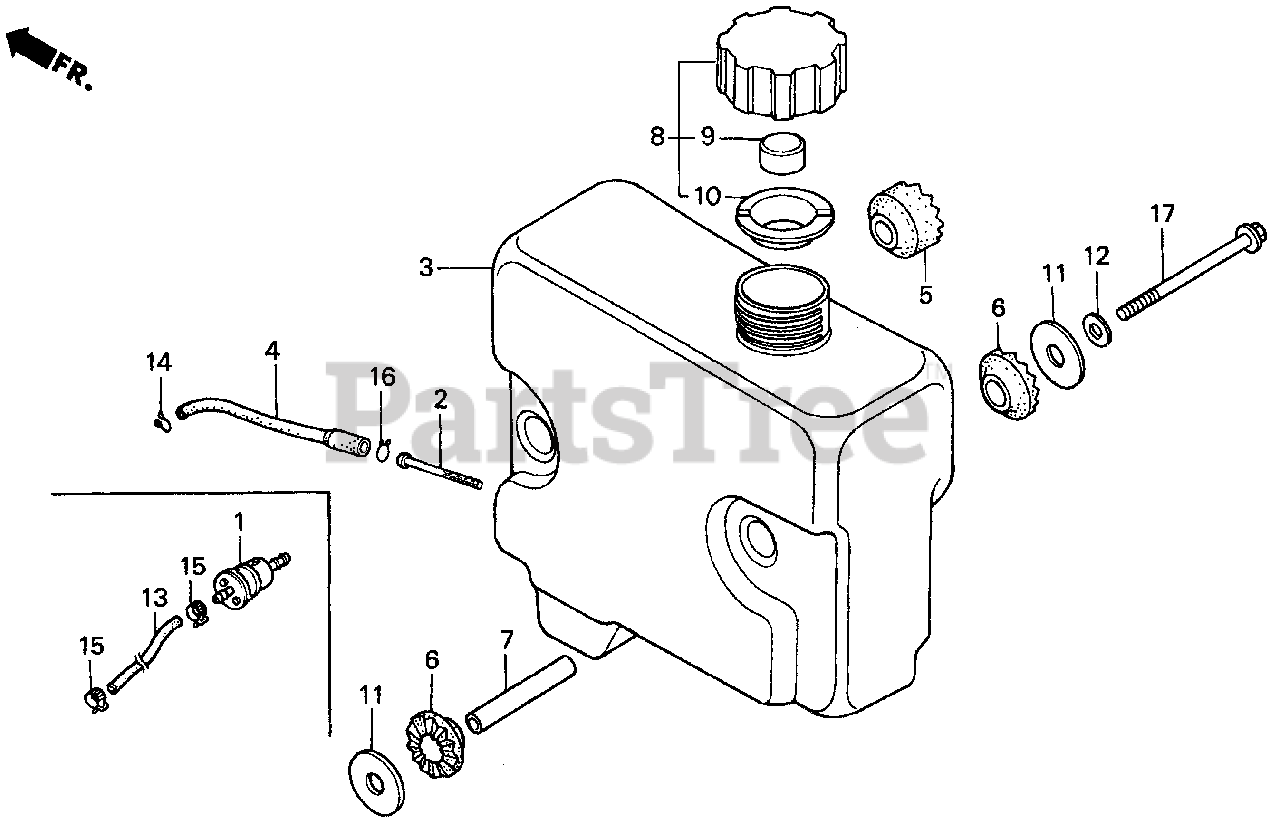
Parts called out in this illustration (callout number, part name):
2	FILTER, FUEL
3	TANK, FUEL
4	TUBE, FUEL
5	RUBBER B, TANK MOUNTING
6	RUBBER B, TANK MOUNTING
7	COLLAR, TANK SETTING
8	CAP ASSY., FUEL TANK
9	SPONGE, FUEL CAP BREATHER
10	GASKET, FUEL CAP
11	WASHER, TANK MOUNTING
12	WASHER, PLAIN (8MM)
14	CLIP, TUBE (B8)
16	CLIP, TUBE (C11)
17	BOLT, FLANGE (8X95)
